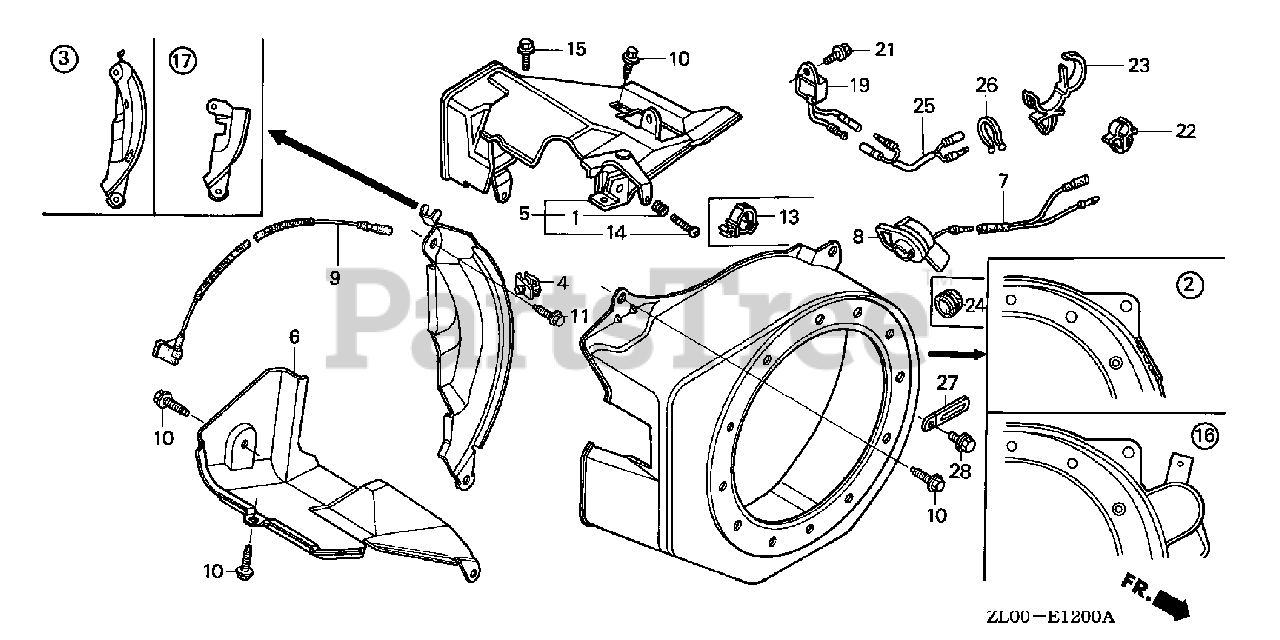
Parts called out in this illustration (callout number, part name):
6	SHROUD
9	WIRE, STOP SWITCH
9	WIRE, STOP SWITCH (370MM)
10	BOLT, FLANGE (6X12) (CT200)
16	COVER, FAN *R8* (BRIGHT RED)
17	PLATE, SIDE (STARTER MOTOR)
22	CLIP, CORD
23	STRAP, WIRE HARNESS (25MM) (BLACK)
